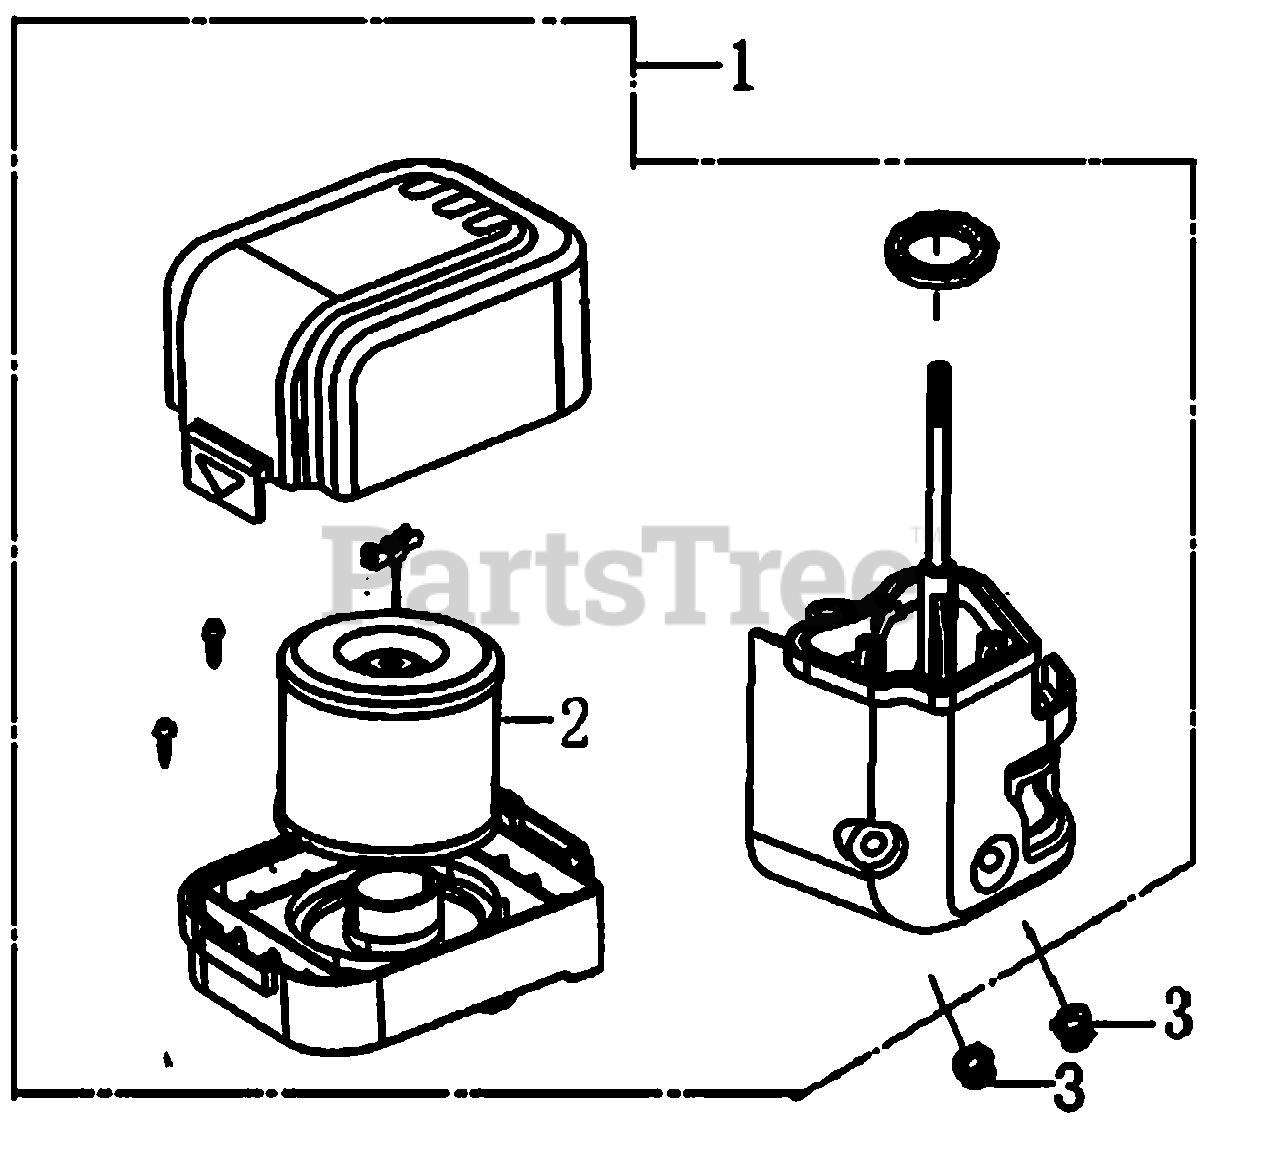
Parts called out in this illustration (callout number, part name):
1	AIR CLEANER ASSY.
2	ELEMENT, AIR FILTER
3	NUT, FLANGE 6MM
